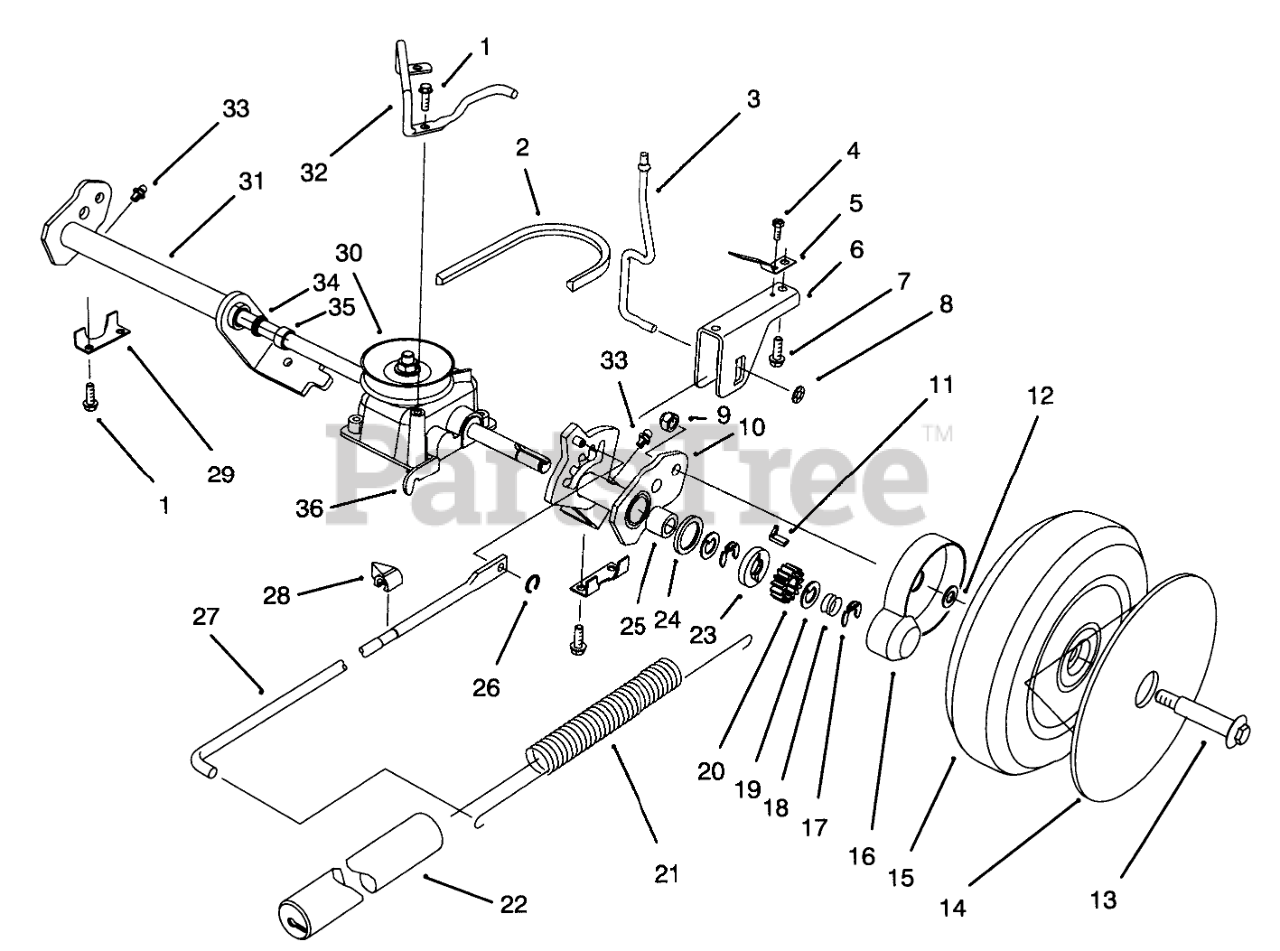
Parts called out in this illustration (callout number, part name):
1	SCREW-HWH
2	V-BELT
3	TRIGGER ROD
4	SCREW 8 - 32 X 250
5	SPRING - TRIGGER RET
6	SADDLE - HOC
7	SCREW
8	PUSHNUT
9	NUT-HEX
10	Arm-Pivot L.H. (Incl. Ref.#25,&33-35)
11	KEY-ROCKING, LH
12	SPACER-COVER, WHEEL
13	BOLT-WHEEL
14	COVER-WHEEL
15	WHL & TIRE ASSEMBLY
16	COVER-WHEEL
17	RING-CLIP, LOCKING
18	SPRING-COMPRESSION
19	WASHER-THRUST, KEYED
20	GEAR-PINION
21	SPRING-COUNTERBALANCE
22	COVER-SPRING
23	WASHER-CLUTCH
24	RING-FRICTION
25	BEARING-ROLLER
26	GRIP RING
27	LINK ROD
28	INDICATOR-HEIGHT OF CUT
29	REAR SECURING PLATE
30	GEAR CASE ASSY
31	Arm-Pivot R.H. (Incl. Ref.#25,&33-35)
32	Retainer Belt
33	FITTING-GREASE
34	SEAL-OIL
35	BUSHING
36	Bracket-Traction
